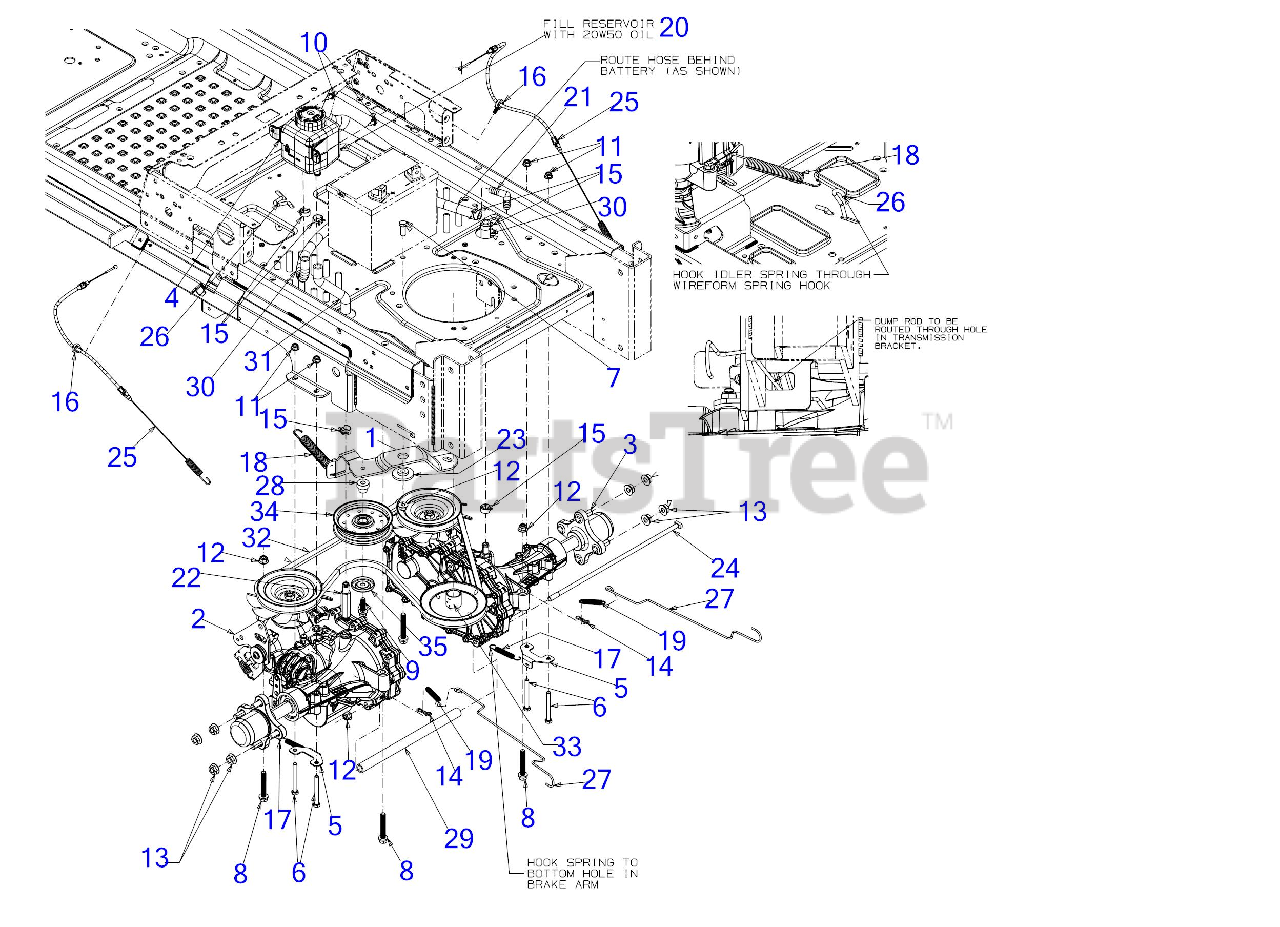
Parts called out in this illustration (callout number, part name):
1	IDLER BRACKET ASSEMBLY
2	TRANSMISSION ASSEMBLY (LH)
3	TRANSMISSION ASSEMBLY (RH)
4	HYDRAULIC TANK
6	HEX SCREW 5/16-18 x 2.75
7	SCREW 3/8-16 x 1 GR5
8	SCREW 3/8-16 x 2.25 GR5
9	SCREW 3/8-16 X1.250
10	SCREW 1/4-20X.625
11	FLANGE LOCK NUT 5/16-18
13	HEX FLANGE NUT 7/16-14
14	BOW TIE COTTER PIN 1/4-5/16
15	FUEL HOSE CLAMP
16	CABLE RETAINER CLIP
17	EXTENSION SPRING .38 OD x 3.25 LG
18	EXTENTION SRING .75 DIA. x 6.85
19	EXTENSION SPRING .380 ODX 2.000 LG
21	90 DEGREE NYLON FITTING
22	EXTENSION FITTING 9/16-18
23	SHOULDER SPACER
24	SUPPORT TUBE ROD
25	PARK BRAKE CABLE
26	IDLER SPRING HOOK
28	SHOULDER SPACER
29	TRANSMISSION SPACER .75OD x 11.31
30	FUEL LINE 1/2" ID
31	EXPANSION TANK HOSE
32	TRANSMISSION DRIVE BELT A x 67
32	Cub Cadet TRANS DRIVE BELT A x 67 RZT
32	Troy-Bilt TRANSMISSION DRIVE BELT
33	TRANMISSION DRIVE PULLEY
34	IDLER PULLEY 4.25 DIA
35	IDLER PULLEY CAP
